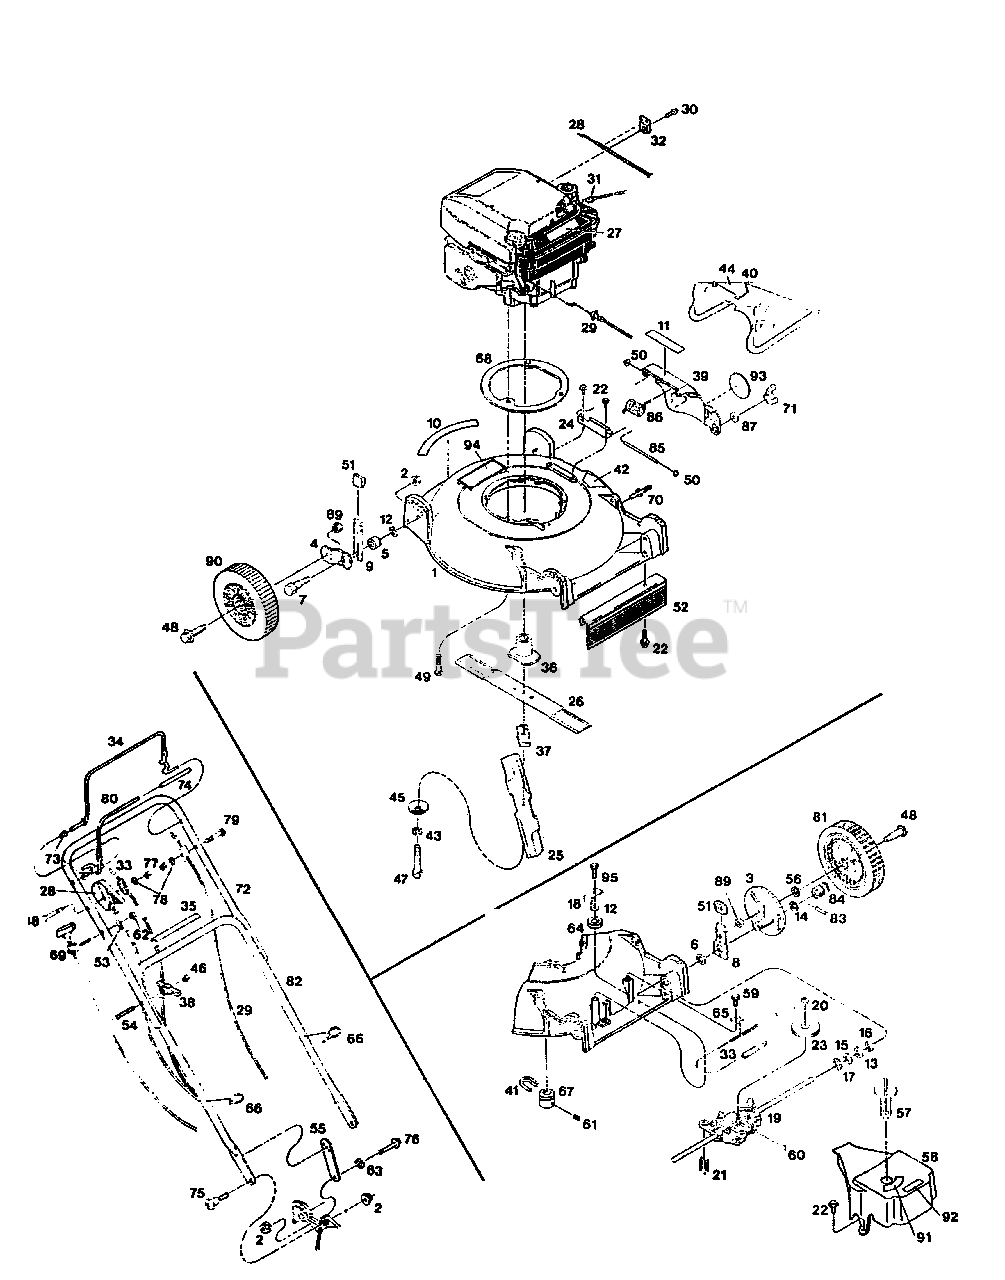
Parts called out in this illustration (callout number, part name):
1	Deck-20" orange 3 spd.
2	Nut-5/16-18 flg. lock
3	Drive wheel support ass'y-blk
4	Wheel arm-blk
5	Spacer-front hgt. adj.
6	Spacer-rear hgt. adj.
7	Bolt-height adjuster
8	Setting lever assy L.H. rear
8	Setting lever assy R.H. rear
9	Setting lever assy. R.H. front
9	Setting lever assy. L.H. front
10	Decal-logo 20"
11	Decal-danger mulch cover
12	Washer-5/16" flat
13	Washer-shim
14	Washer-9/16" flat
15	Washer-9/16" flat
16	Washer-9/16" wave
18	Retainer bracket
19	Transmission-3 spd.
20	Nut-10mm lock
21	Spring-compression
22	Screw-1/4-20 x 3/4" hex hd. tap
23	Pulley-transmission
24	Bracket-hinge
26	Blade-recut 20"
27	Decal-blade warning
28	Control-throttle w/cable
29	Cable-engine/blade control
30	Screw-#10-16 x 5/8" tap
31	Rope stop
32	Cable clamp
33	Cable-traction control
34	Bail-engine/blade control
35	Decal-starting instructions
36	Adapter-blade
37	Spacer-blade
38	Wing nut-plastic
39	Cover-mulch 20"
40	Chute deflector assembly
42	Decal-CPSC danger
43	Washer-3/8" lock H.D.
44	Decal-CPSC Danger
45	Washer-3/8" conical
46	Nut-5/16-18 hex
47	Bolt-3/8-24 x 3-1/2" HHCS Gr. 8
48	Bolt-wheel
49	Bolt-3/8-16 x 1-3/4" HHCS Gr. 5
50	Nut-1/4 push-on
51	Plastic tip-height adjuster
52	Trailing shield-plastic
54	Bolt-handle
55	Handle support
56	Washer-3/8" flat
57	Shift knob-plastic
58	Drive cover 3 spd.
59	Screw-1/4-20 x 1/2" hex hd. tap
60	Key-transmission
61	Set screw 1/4-20 x 3/8"
62	Nut-1/4-20 lock
63	Washer-5/16" wave
64	Pulley-1 1/4" dia.
65	Clamp-drive cable
66	Cable tie
67	Drive pulley
68	Engine ring-red
69	Eyebolt-1/4-20
70	Stud-1/4-20 x 3/4"
71	Wing nut-1/4-20 nylon insert
72	Handle-upper
73	Bushing-drive bail
74	Sleeve-drive bail
75	Bolt-handle mtg.
76	Bolt-handle supt.
77	Nut-1/4-20 hex
78	Washer-1/4" star
79	Screw-1/4-20 x 1-1/2" truss hd.
80	Bail-ground drive control
81	Wheel-8" power propelled
82	Handle-lower
83	Drive pin
84	Pinion R.H. 3 spd.
84	Pinion L.H. 3 spd.
85	Rod hinge
86	Spring-mulch cover
87	Washer-1/4" flat
88	Bolt-1/4-20 x 2-1/2" HHCS
89	Nut-3/8-16 jam lock
91	Decal-3 spd. shift inst.
92	Decal-3 spd. belt cover
93	Decal-3 in 1
94	Decal-convertible mulcher
95	Screw-1/4-20 x 1" hex hd. tap
